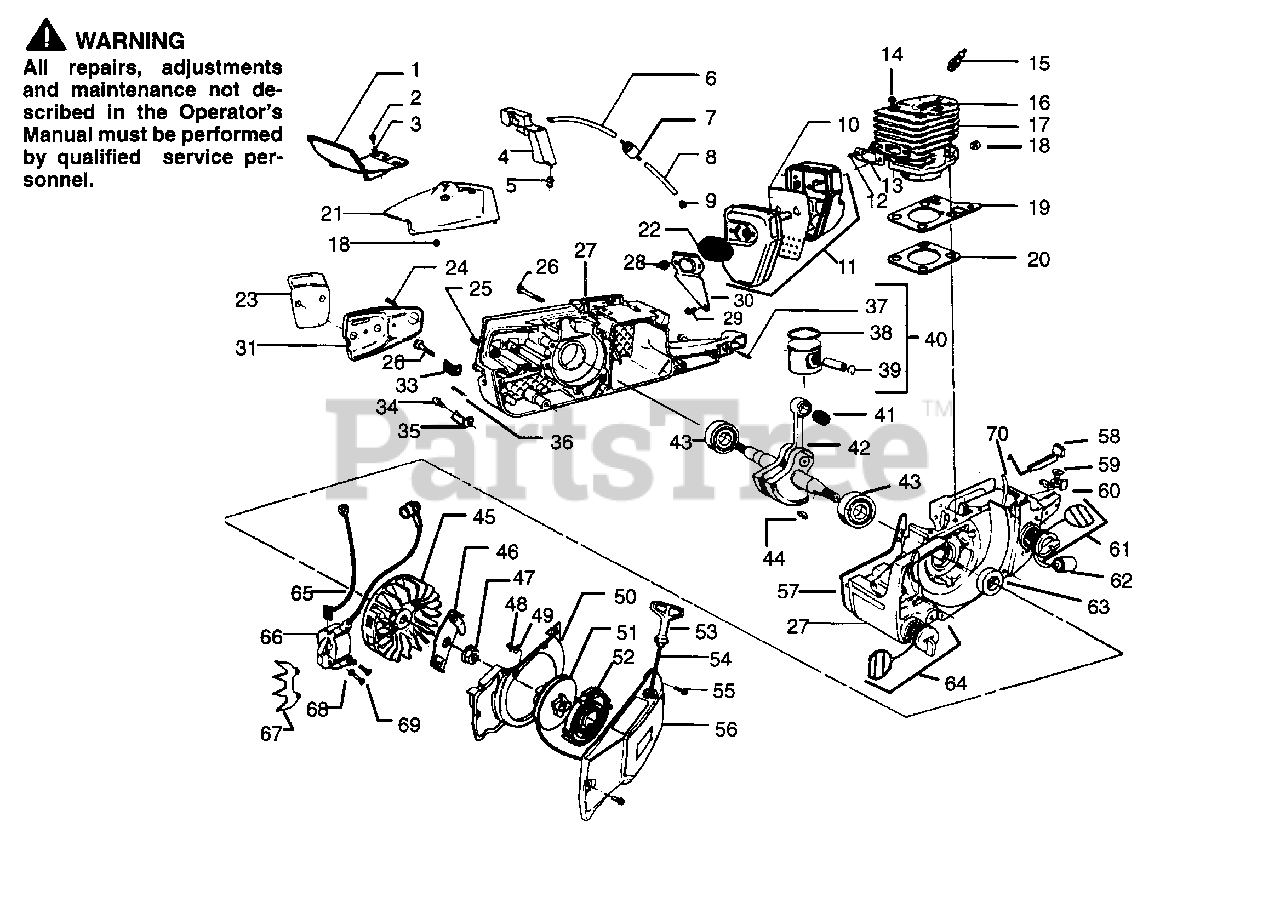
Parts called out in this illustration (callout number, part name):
1	Handguard
4	Expansion Bottle
5	Vent Grommet
7	Vent Valve
10	Baffle Plate
11	Muffler Ass'y. (Inc.10)
15	Spark Plug
17	Cylinder
19	Insulator
20	Cylinder Gasket
21	Cylinder Cover
22	Spark Arrestor
23	Guide Plate (Outer)
27	Crankcase Ass'y.
28	Nut
31	Guide Plate (Inner)
33	Adjustment Stop Plate
35	Chain Catcher
36	Pin
38	Piston Ring
39	Retainer
40	Piston Kit (Inc. 38,39, Pin)
41	Needle Bearing
42	Crankshaft Ass'y.
44	Flywheel Key
45	Flywheel
46	Flywheel Plate
48	Screw
50	Air Baffle
51	Starter Pulley
52	Starter Spring
53	Starter Handle
54	Starter Rope
56	Fan Housing
57	Gasket Kit
58	Choke Knob
60	Switch Knob
61	Fuel Cap Ass'y.
62	Fuel Filter
64	Oil Cap Ass'y.
65	Lead Wire
66	Ignition Module
70	Fuel Line
